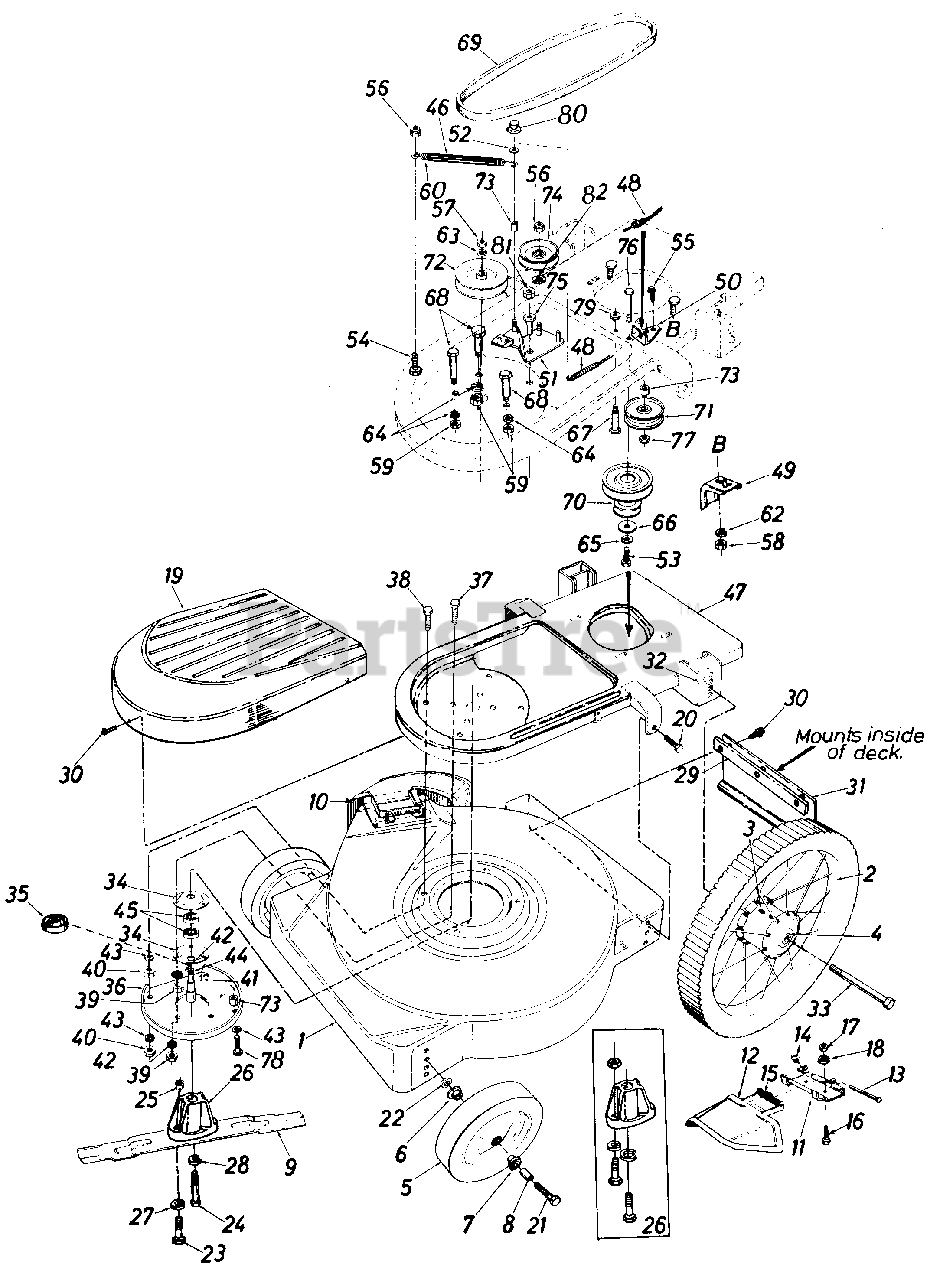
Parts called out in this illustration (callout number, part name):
3	Oil Cap
4	Ball Bearing
5	Wheel Ass'y. Comp. 8 x 1.75 (Twinline Tread)
6	Flanged Ball Bearing 3/8" I.D.
7	Flanged Ball Bearing 1/2" I.D.
8	Spacer
9	22" Blade
10	Chute Deflector Ass'y. Comp.
11	Adapter Plate
12	Deflector Ass'y.
13	Pivot Pin
14	Push Cap 1/4" Rod
15	Torsion Spring
16	Hex Bolt 1/4-20 x .50" Lg.
17	Hex Nut 1/4-20 Thd.
18	L-Wash. 1/4" I.D.
19	Blade Spindle Cover
20	Hex Sems Scr. 3/8-16 x .62"
21	Hex Bolt 3/8-16 x 2.0" Lg.
22	Bell-Wash. .400" I.D. x .88"
23	Hex Bolt 5/16-4 x 1.00" Lg.
24	Hex Bolt 3/8-24 x 2.25" Lg.
25	Hex Nut 5/16-24 Thd.
26	Blade Adapter Kit
27	L-Wash. 5/16" I.D.
28	L-Wash. 3/8" I.D.-H.D.
29	Retaining Strip
30	Hex Wash. Hd. AB-Tap Scr. 1/4" x .62" Lg.
31	Rear Flap Ass'y.
32	Bell-Wash. .400" I.D. x .88"
33	Rear Axle Bolt
34	Bearing Housing
35	Bearing Shield
36	Blade Reinforcement Plate
37	Hex Bolt 5/16-24 x 1.25" Lg.
38	Hex Bolt 3/8-24 x 1.25" Lg.
39	Hex Nut 5/16-24 Thd.
40	Hex Nut 3/8-24 Thd.
41	#6 Hi-Pro Key 5/32" x 5/8" Dia.
42	L-Wash. 5/16" I.D.
43	L-Wash. 3/8" I.D.*
44	Blade Spindle
47	Frame Ass'y.
48	Clutch Cable-39.0"
49	Belt Keeper Ass'y.
50	Clutch Cable Brkt.
51	Idler Brake Brkt. Ass'y.
52	Fl-Wash. .343" I.D. x .687" O.D. x .063
53	Hex Bolt 3/8-24 x 1.00" Lg.
54	Hex Bolt 1/4-20 x .75" Lg.
55	Hex Wash. Hd. AB-Tap Scr. 1/4" x .62 Lg.
56	Hex Cent. L-Nut 1/4 -20 Thd.
57	Hex Jam Nut 5/8-11 Thd.
58	Hex Nut 5/16-18 Thd.
59	Hex Nut 3/8-16 Thd.
60	Extension Spring
62	L-Wash. 5/16" I.D.
63	L-Wash. 5/8" I.D.*
64	L-Wash. 3/8" I.D.
65	L-Wash. 3/8" I.D.-H.D.
66	Fl-Wash. .406" I.D. x 1.25" O.D.
67	Shld. Bolt .498" Dia. x 1.64"
68	Shld. Bolt .498" Dia. x 1.450"
69	V-Belt 1/2" x 44.0" Lg.
70	Engine Pulley
71	Flat Idler Pulley
72	1/2" V-Pulley .503" I.D. x 4.50" O.D.
73	Spacer .376 I.D. x .622 O.D. x .44" Lg .
74	4.0" Idler Pulley
75	Shoulder Spacer
76	Hex Bolt 3/8-24 x 1.75" Lg.
77	Hex L-Nut 3/8-24 Thd.
78	Hex Bolt 3/8-24 x 1.5" Lg.
79	Hex L-Nut 3/8-16 Thd.
80	Push Cap 1/4
81	Hex Jam Nut 3/8-24 Thd.
82	Fl-Wash. .406 I.D. x 1.25 O.D. x .172 Thk.
